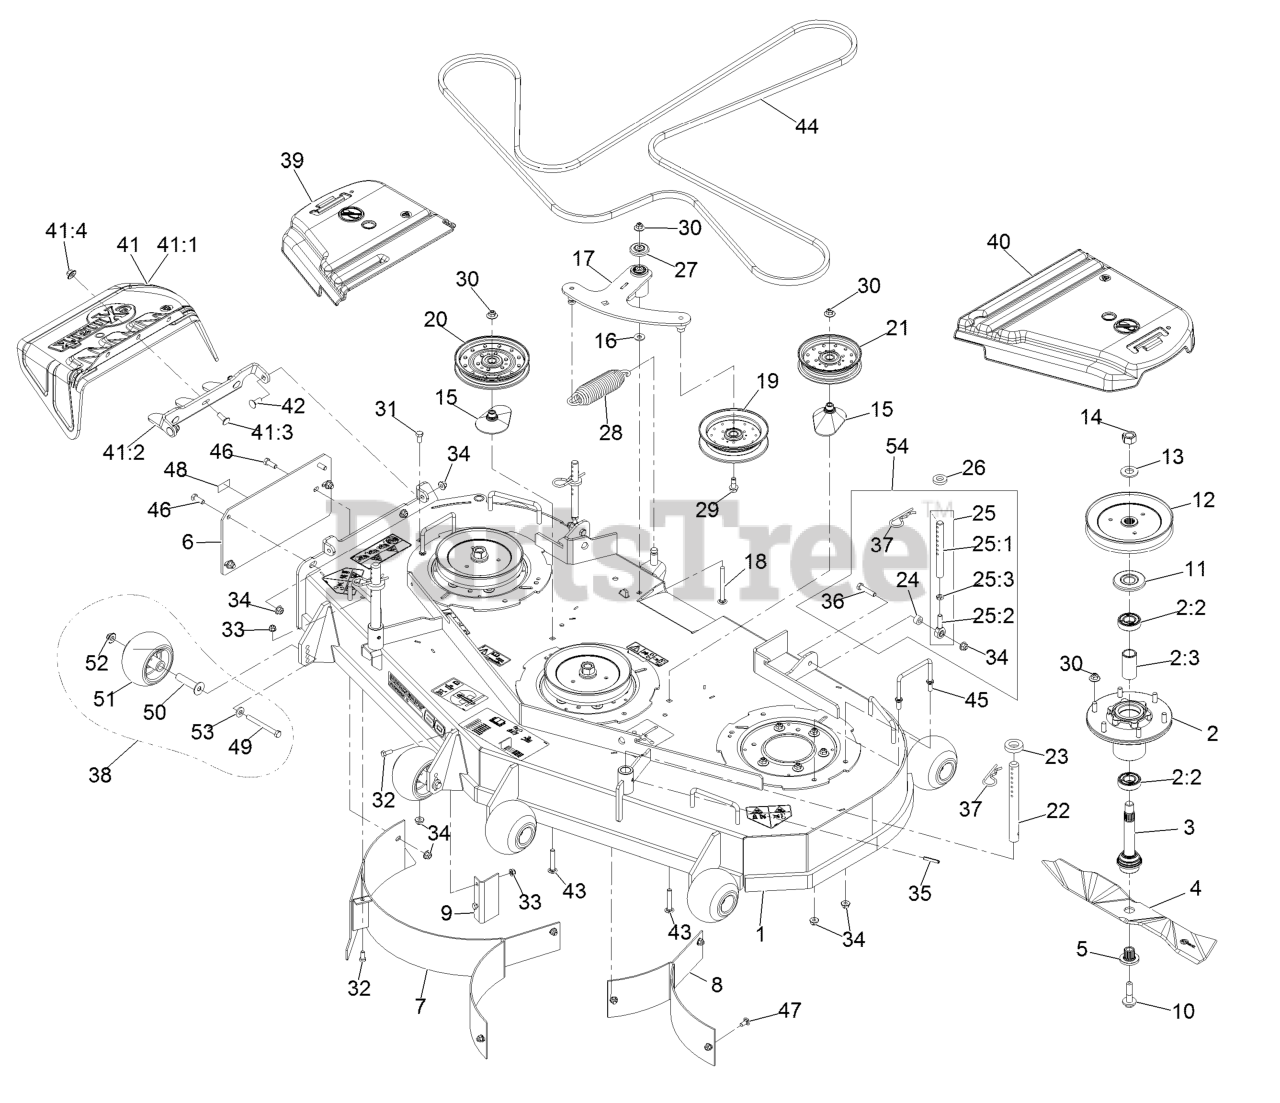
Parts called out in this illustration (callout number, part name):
1	ASM, Deck W/ Decals, 60"
2	ASM-Cutter Hsg With Bearings
2:2	Bearing-Ball
2:3	Spacer-Bearing
3	ASM-Spindle And Seal
4	Blade, Solid
4	Blade, Low Lift
4	Blade, Mulching
4	Blade, Notched
4	Blade-Extreme 2, 20.50"
5	Bushing, Splined
6	Plate, Mulch Cover Mk604
7	Wld, Baffle RH Mk604
8	Wld, Baffle LH Mk604
9	Baffle, Blocker Mk604
10	Screw-Sems 1/2-20 X 2.19
11	Guard,Bearing Top .989
12	Sheave,Blade Drive 7.25
13	Washer-Spring Disc 3/4
14	Nut-Hex
15	Spacer-Pulley
16	Washer-3/8 Std
17	ASM, Deck Idler
18	Bolt-Carriage 3/8-16 X 3 3/4
19	Idler-Pulley, Flanged
20	Idler-Pulley, Flat
21	Pulley-Idler, Flat
22	Rod, Deck Support
23	Spacer-Deck Support
25	Link Assy
25:1	Link, Rear Deck Support
25:2	Balljoint
25:3	Nut-Jam 3/8-24
26	Spacer-Blade Drive
27	Guard-Top
28	Spring-Extension
29	Screw-Hfh
30	Nut-Nyloc 3/8-16 Flg
31	Screw-HH 3/8-16 X 3/4
32	Screw-HH 5/16-18 X 3/4
33	Nut-Nyloc 5/16-18 Flg
34	Nut-Nyloc 3/8-16 Flg
35	Rollpin 1/4 X 1 1/2
36	Screw-HH 3/8-16 X 1 3/4
37	Hairpin-Cotter #206
38	Kit, Anti-Scalp Roller
39	Cover-Belt, RH
40	Cover-Belt, LH
41	ASM,Discharge Chute
41:1	Chute, Discharge
41:2	Bracket,Discharge Chute
41:3	Bolt-Carriage 3/8-16 X 1
41:4	Nut-Nyloc 3/8-16 Flg
42	Bolt-Carriage 3/8-16 X 1
43	Bolt-Carriage 3/8-16 X 2 1/4
44	Belt, Deck Drive
45	Wireform-Cover
46	Screw-HH 3/8-16 X 1
47	Bolt-Carriage 5/16-18 X 3/4
48	Decal-Patent
49	Screw-HH 3/8-16 X 3 3/4 GR 8
50	Axle, Roller
51	Roller-Anti-Scalp
52	Nut-Nyloc 3/8-16 Flg
53	Washer-Spring Disc 3/8
54	Kit, Support Link W/Pin
